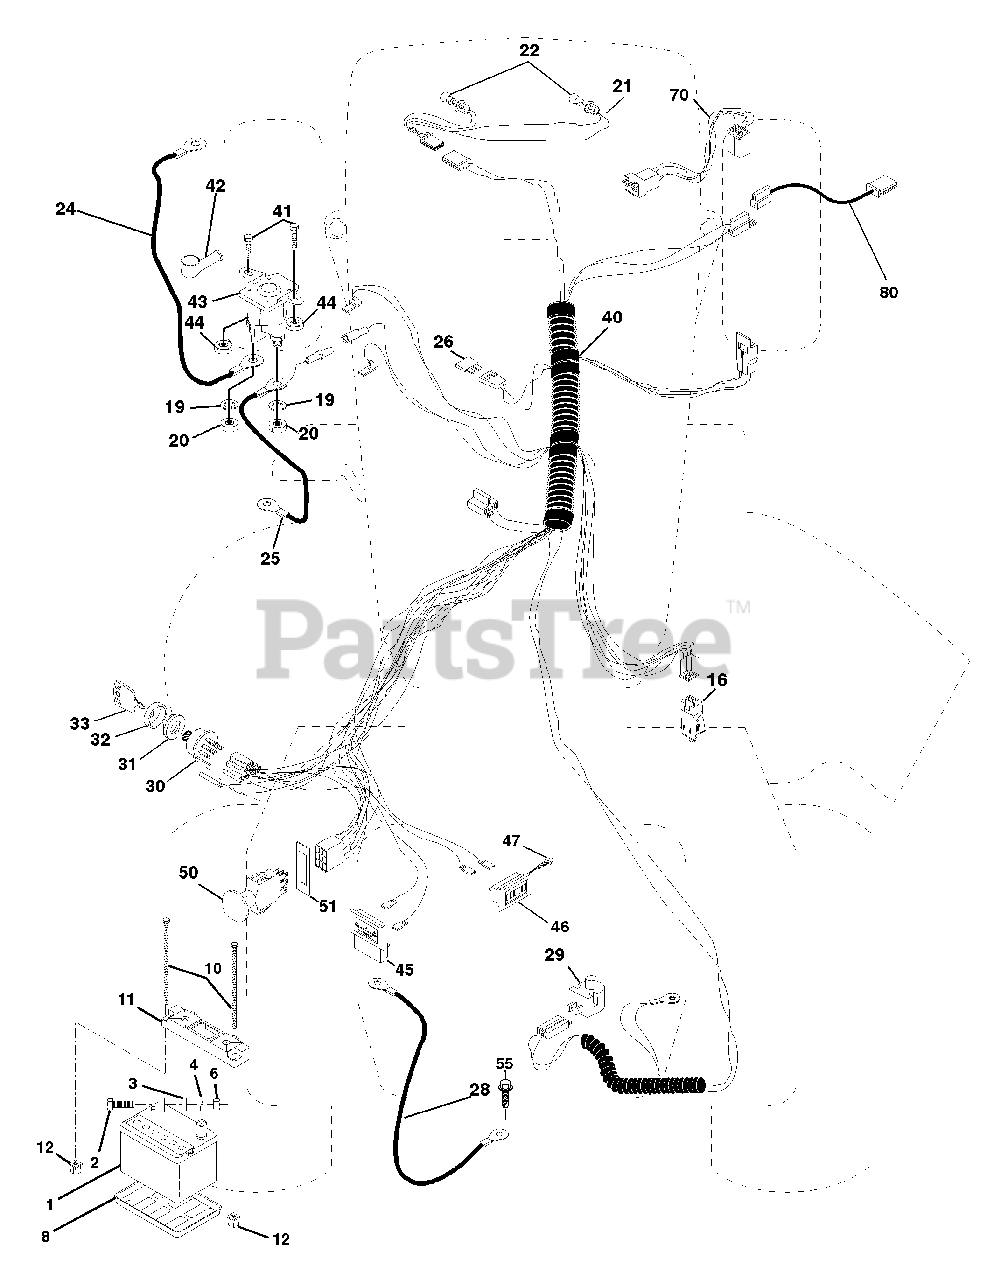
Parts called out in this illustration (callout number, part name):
1	Battery 12 Volt 25 AMP
2	Bolt Hex Hd 1/4-20 unc X 3/4
3	Washer 9/32 X 5/8 X 16 Ga.
4	Washer Lock Hvy Helical 1/4
6	Nut Fin Hex 1/4-20 Unc
8	Tray Battery 7.80 x 5.25 Blk
10	Bolt Btr Frt 1/2-20 x 7.5 Zinc
11	Holddown Battery Front Mount
12	Nut Push Nylon 1/4" Battery Frt
16	Switch Interlock Push-In
19	Washer Lock 1/4
20	Nut Jam Hex 1/4-20 Unc
21	Harness Asm Light W/4152j
22	Bulb Light #1156
24	Cable Battery 6 Ga 11" red
25	Cable Battery 6 Ga 44" red w/16 wire
26	Fuse 30 AMP Auto Green
28	Cable Ground 6 Ga 21" black
29	Switch Plunger Nc Gray
30	Switch Ign 4 pos w/lights
31	Nut Ignition
32	Cover Sw Ignition
33	Key Ign Modelled Generic
40	Harness Ign.
41	Bolt Blk Fin Hex 1/4 - 20 x 1/2
42	Cover Terminal Red
43	Solenoid
44	Nut Keps Hex 1/4-20 Unc
45	Ammeter Rectangular 6 Amp
46	Meter Hour
47	Screw 10-24 x 1/2 Black
50	Switch PTO 3PDT Black Delta 96
51	Ring Retainer PTO
55	Screw Thdrol 5/16-18 x 1/2 Tyt
70	Harness, Eng Kohl Cmd-L Dual
80	Harness Clutch Evx
81	Relay Asm.
